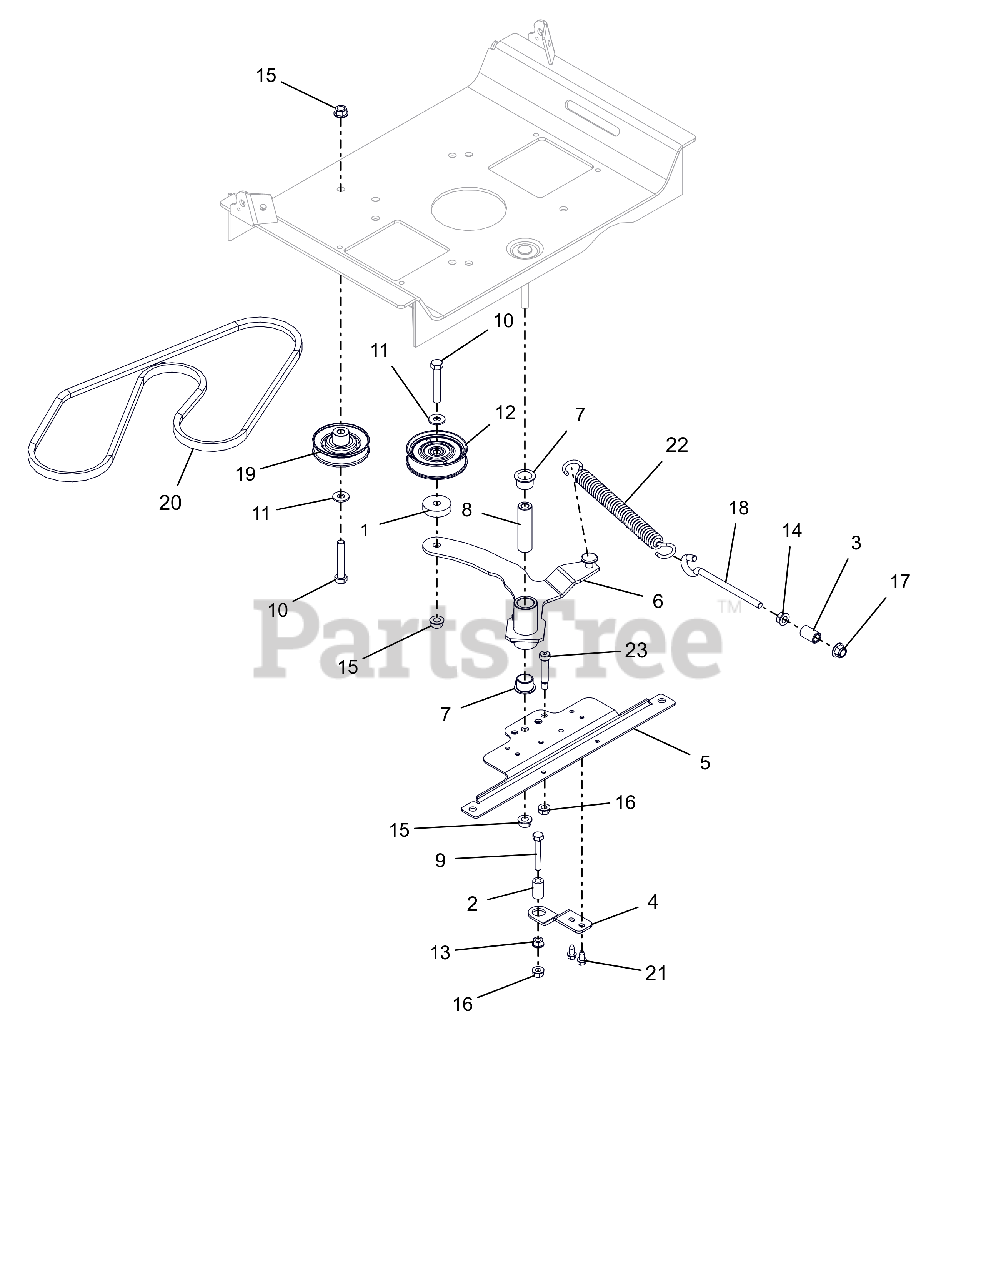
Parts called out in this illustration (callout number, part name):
1	SPACER, .39 X 1.50 X .380
2	SPACER, RUBBER 5/16 IDX1.0 LG
3	SPACER, .375X.625X.970 (PM)
4	BRKT, CLUTCH STOP
5	BRKT, DRIVE IDLER MOUNTING
6	WLDMT,GRD DRIVE IDLER ARM-LGR
7	BSHG-FLG 0.75X0.875X.625X1.125
8	BUSHING, SLEEVE .38X.750X2.78
9	BLT, HEX .31-18X2.00 G5 ZCC
10	BLT,HEX .38-16X2.25 G5 ZCC
11	WSHR,FLT .375X.875X.083 ZCC
12	IDLER, FLAT - 3.05" X .75"
13	NUT,SPNLK-FLG .31-18 G5 ZCC
14	NUT, SPNLK-FLG .38-16 G5 ZCC
15	NUT-LK-TOP-FLG .38-16 ZC120
16	NUT-LK-TOP-FLG .312-18 GF ZCC
17	NUT,NYL-FLG .38-16 GF ZCC
18	BOLT,.38-16 X 4.25-.62 DIA EYE
19	IDLER, V-3.000 OD
20	V-BELT, A-RAW EDGE
21	SCR-TAP .25-20X.50 HWH ZCC
22	SPRING, EXTENSION
23	BLT-SHLDR .38X1.5X.31-18 SLT Y
